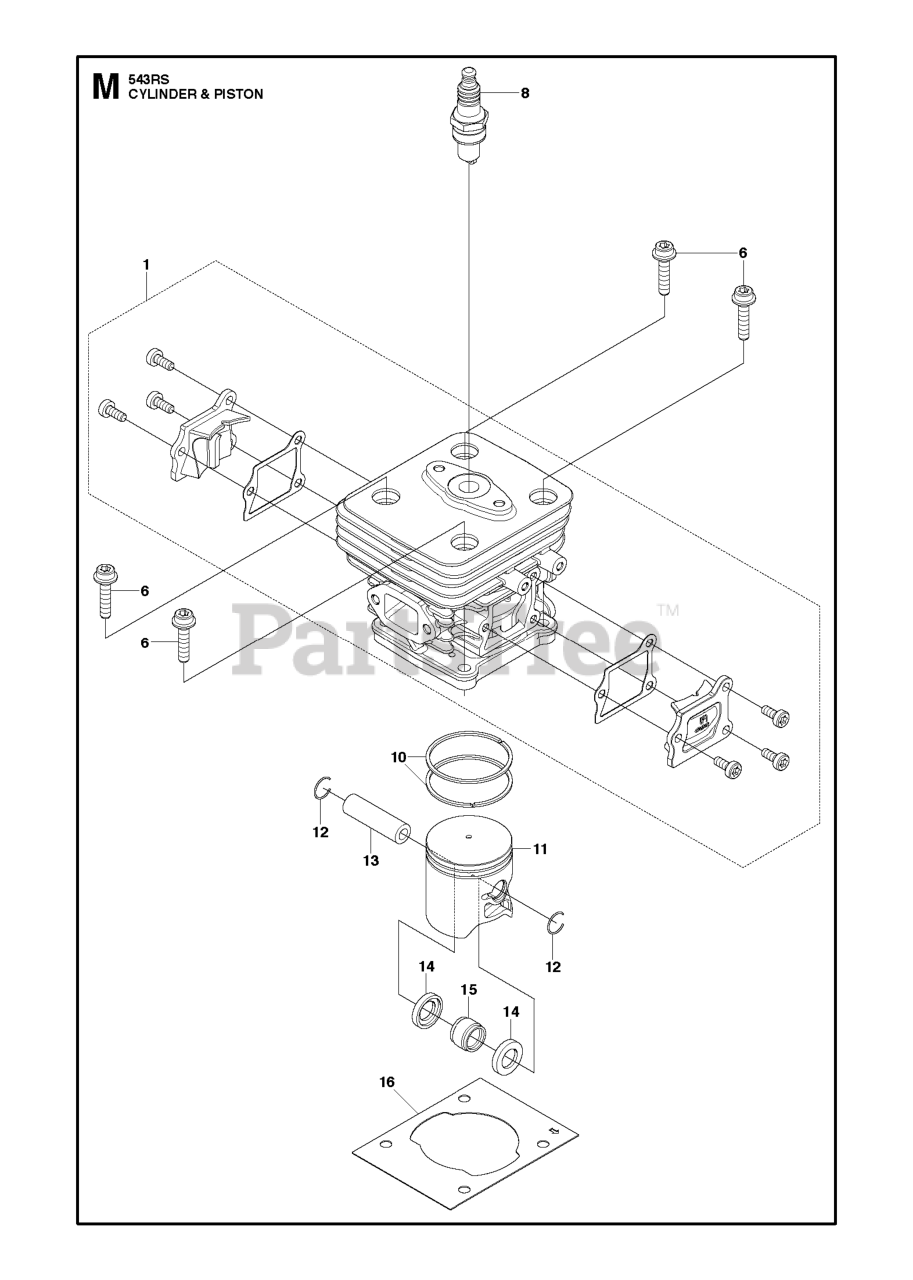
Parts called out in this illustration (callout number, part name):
1	SEAT.TH150.MS498.GRY.HUSQ.TEX
2	BRKT.PIVOT.FENDER
6	NUT
7	SPRING COMPRESSION
8	BOLT.5/16-18UNCX3/4 W/SEMS.BLK
10	PAN.ASM.SEAT.3PT
21	BOLT.5/16-18X5/8.SHOULDER
37	NUT.71038.31-18.HEX.NYLOCK
40	HANDLE.SLIDE.SEAT.TEX.GREY
41	SPRING.LATCH.SEAT.TEX
44	WASHER 13/32 X 2-3/8 X 12GA
46	BOLT.3/8-16X1;1.25OD.WSHR.SEMS
